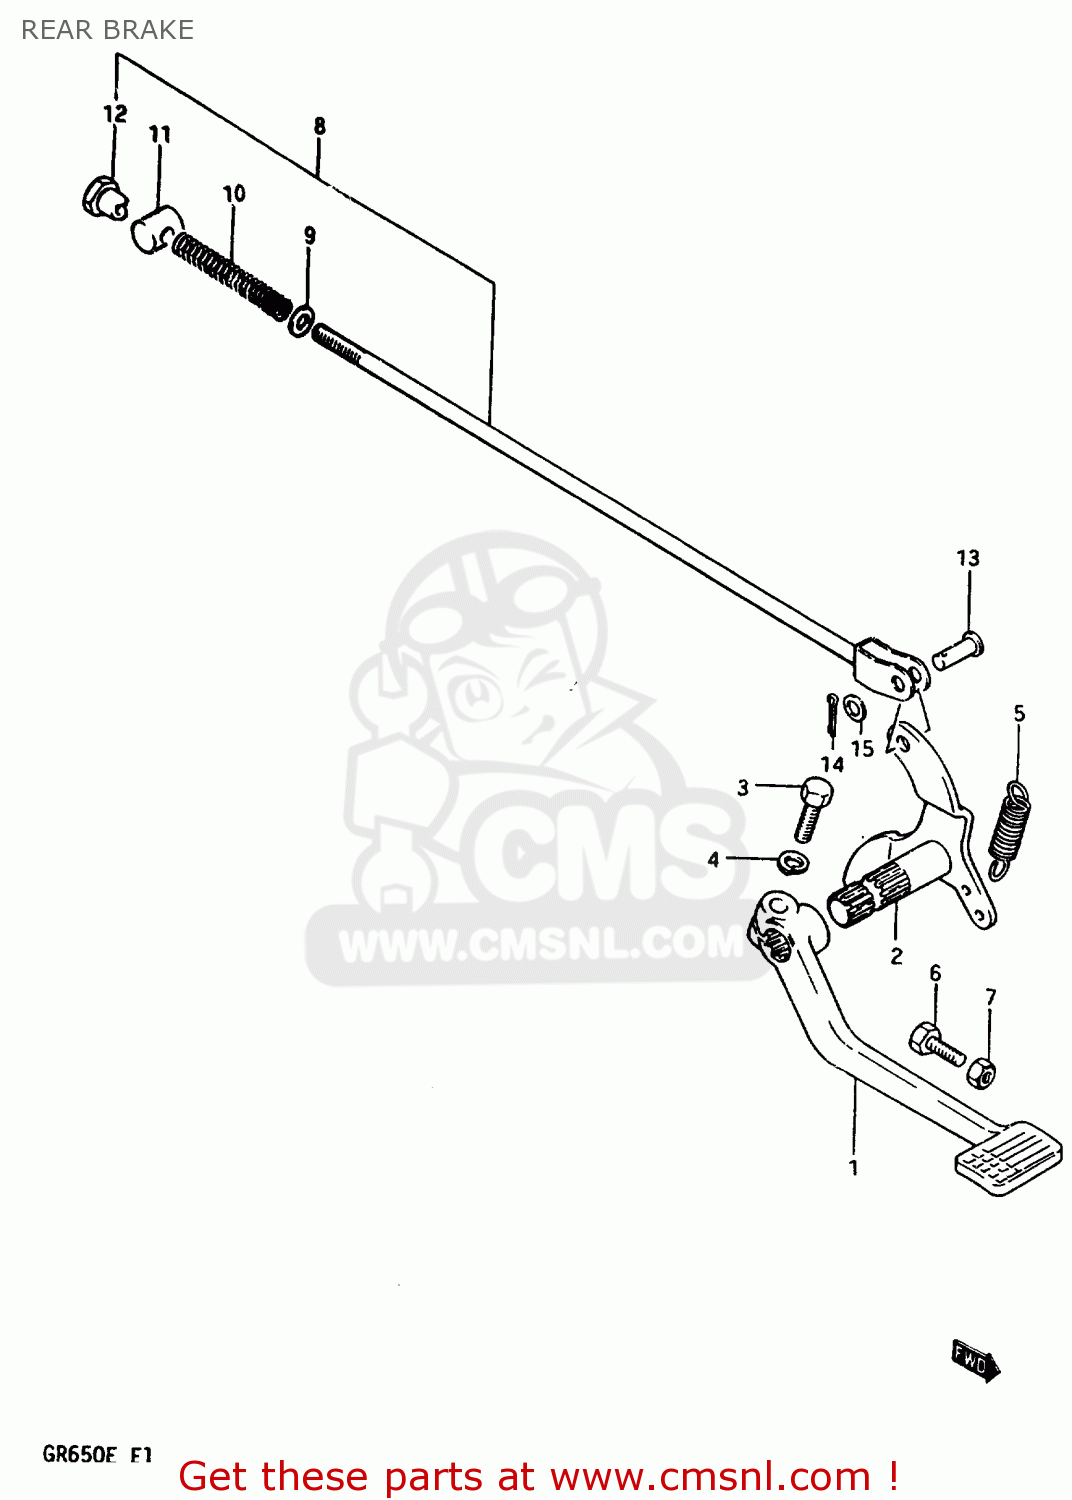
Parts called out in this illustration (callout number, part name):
1	PEDAL,BRAKE
2	ARM,BRAKE ROD
3	BOLT
4	LOCK WASHER
5	SPRING
6	BOLT(6X23)
7	NUT
8	ROD ASSEMBLY,REAR BRAKE
9	WASHER
10	SPRING
11	PIN
12	NUT (6MM)
13	PIN(L:13.5)
14	PIN 20X20
15	WASHER
